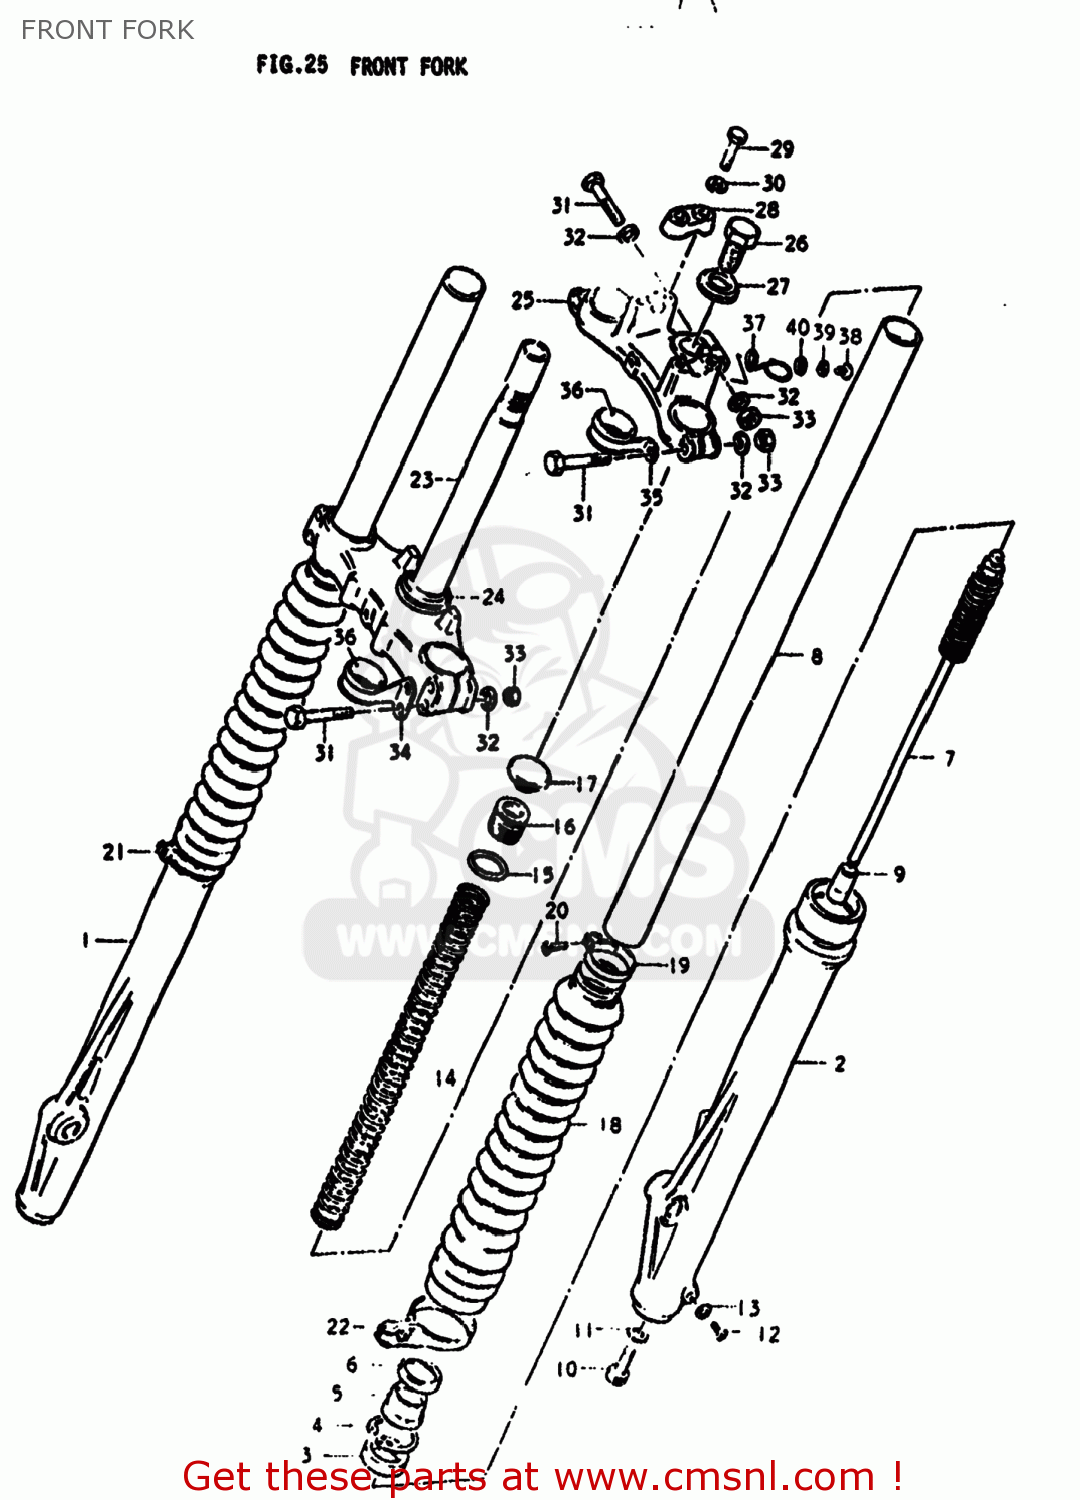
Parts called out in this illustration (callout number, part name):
1	TUBE,OUTER,RIGHT
2	TUBE,OUTER,LEFT
3	OIL SEAL,FRONT FORK
4	CIRCLIP,FORK OIL SEAL
5	DUST SEAL,FRONT FORK
6	GUIDE.FORK DUST
7	CYLINDER,FRONT FORK
8	TUBE,FORK,INNER
9	PIECE,OIL LOCK
10	BOLT,FORK CYLINDER(10X25)
11	GASKET (NAS)
12	SCREW
13	GASKET,DRAIN,PLUG (NAS)
14	SPRING
15	O RING
16	CAP,FORK INNER TUBE
17	CAP,FRONT FORK
18	BOOT
19	BAND,BOOT
20	SCREW
21	BAND,FRONT FORK COVER
22	BAND,FRONT FORK COVER
23	STEM,STEERING
24	RACE,STEERING OUTER LWR
25	HEAD,STEERING STEM
26	BOLT,STEERING STEM HEAD
27	WASHER
28	HOLDER,HANDLEBAR
29	BOLT
30	LOCK WASHER
31	BOLT 8X55
32	WASHER
33	NUT
34	GUIDE,CABLE
35	GUIDE,CABLE
36	SLEEVE
37	CLIP,CABLE
38	SCREW
39	LOCK WASHER
40	WASHER
